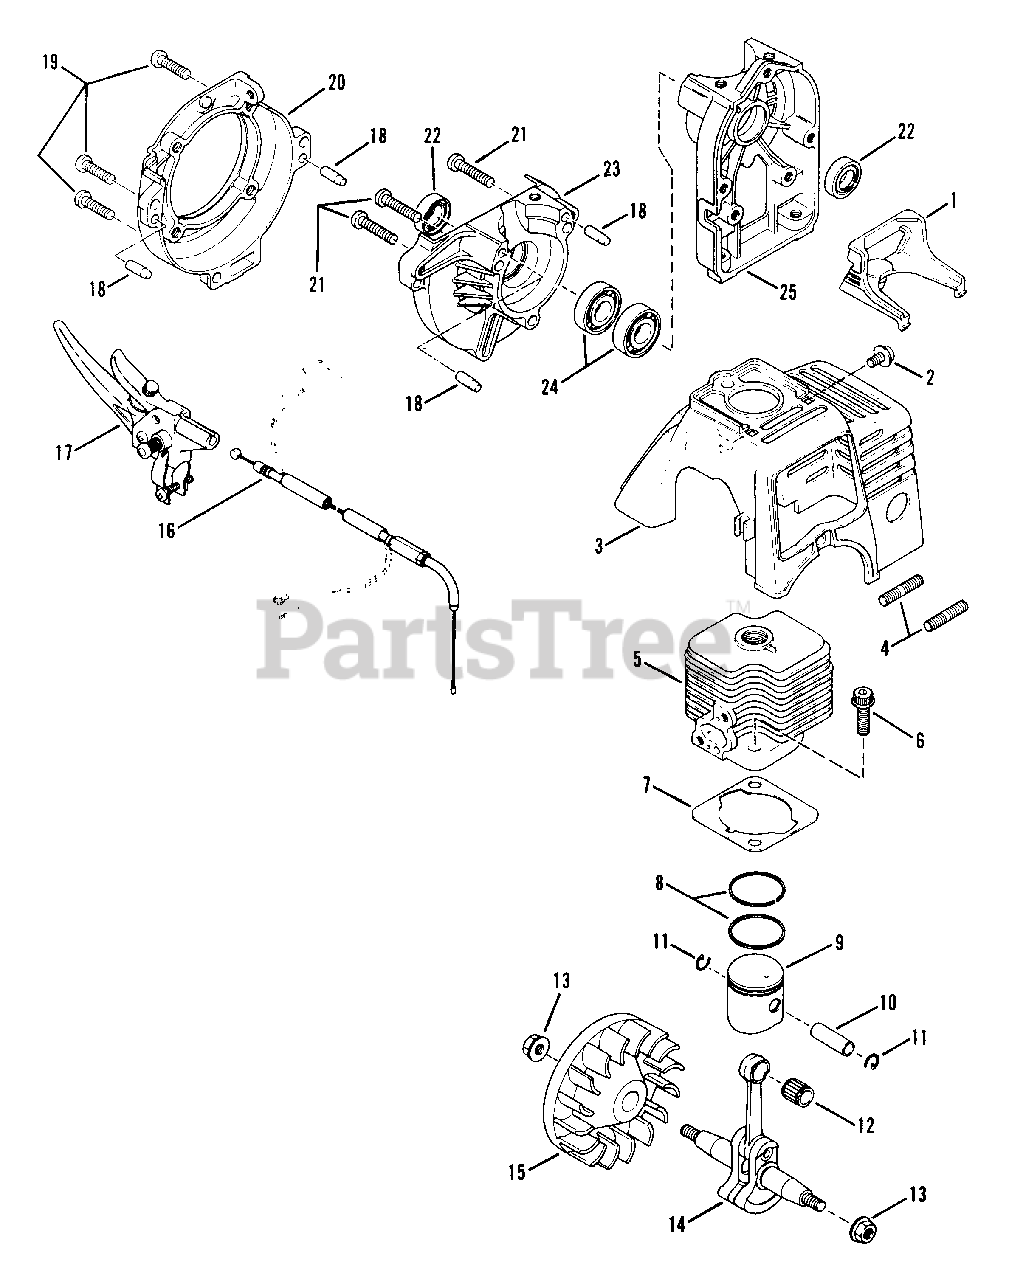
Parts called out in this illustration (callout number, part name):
1	GUARD, Spark Plug
2	SCREW, M5 x 12mm
3	COVER, Cylinder
4	BOLT, Stud, M6 x 16mm
5	CYLINDER
6	BOLT, Flange
7	GASKET, Cylinder
8	RING, Piston
9	PISTON
10	PIN, Piston
11	CLIP, Piston Pin
12	BEARING, Needle
13	NUT, Conical
14	CRANKSHAFT ASSEMBLY
15	FLYWHEEL
16	CABLE, Throttle
17	LEVER, Throttle
18	PIN, Dowel
19	BOLT/WASHER
20	CASE, Fan
21	SCREW, M5 x 25mm
22	SEAL, Oil
23	CASE, Drive
24	BEARING, Ball
25	CASE, Starter
